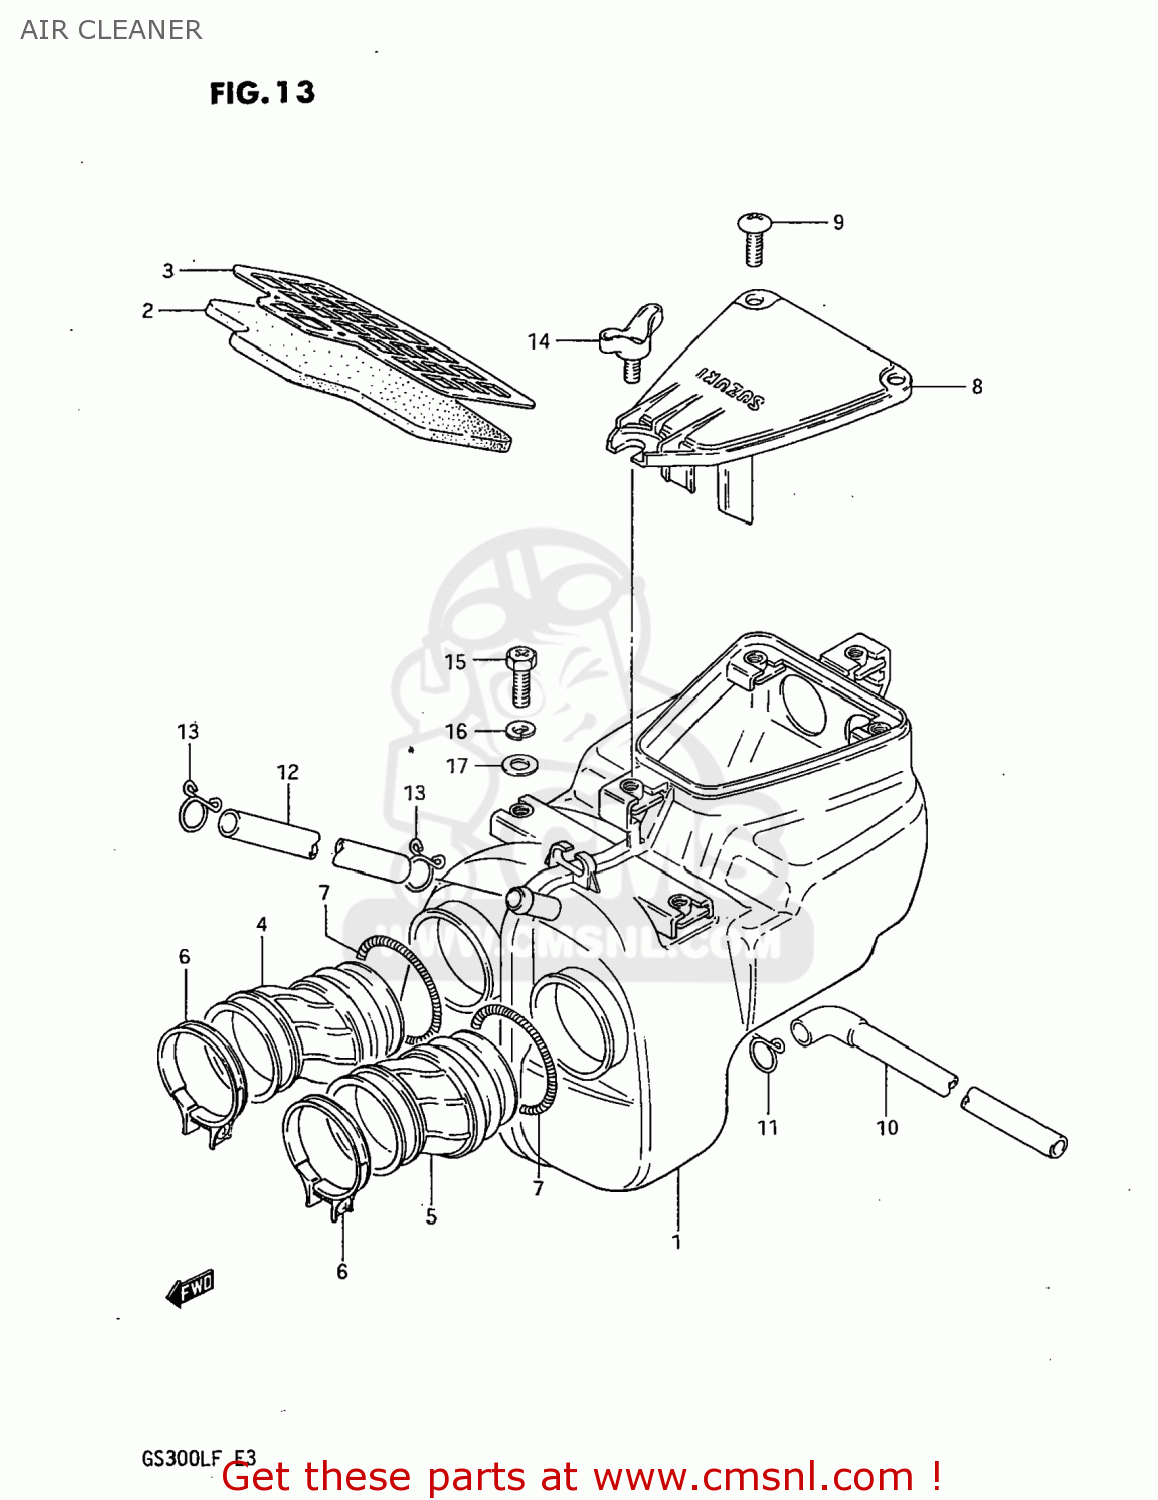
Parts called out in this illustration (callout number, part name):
1	CLEANER ASSEMBLY,AIR
2	FILTER
3	HOLDER,OUTER
4	TUBE,OUTLET,R
5	TUBE,OUTLET,L
6	CLAMP
7	CLAMP,CLEANER SIDE
8	CAP,AIR CLEANER
9	SCREW
10	DRAIN TUBE
11	CLIP
12	TUBE,BREATHER
13	CLAMP
14	BOLT, WING
15	SCREW(6X12)
16	WASHER
